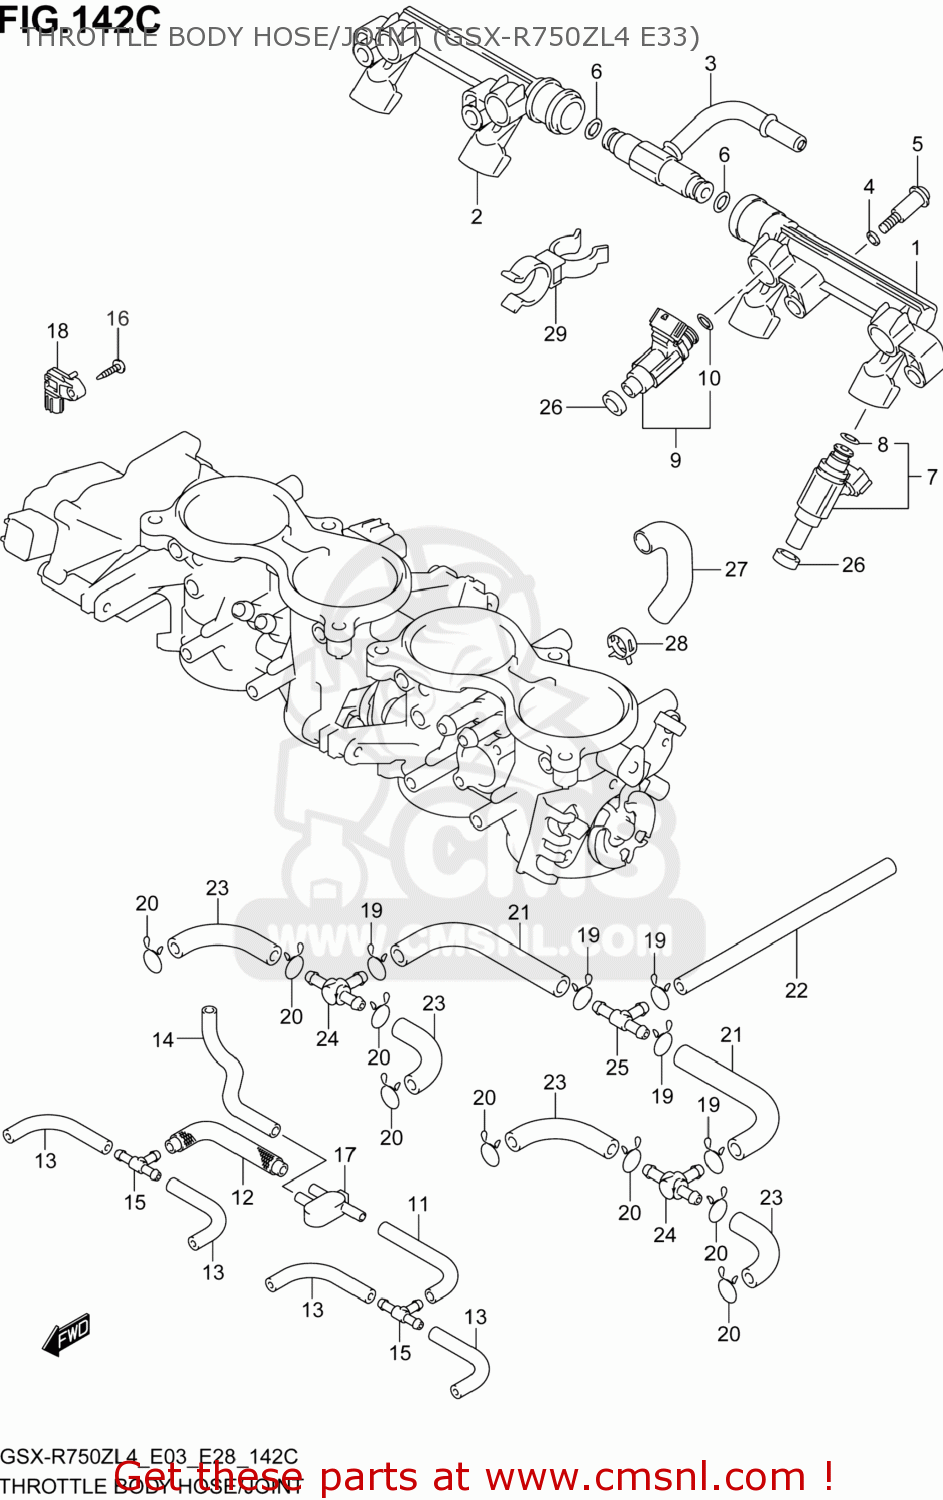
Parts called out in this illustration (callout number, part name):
1	DELIVERY PIPE
2	DELIVERY PIPE
3	NIPPLE ASSY
4	PACKING (NAS)
5	SCREW
6	O RING
7	INJECTOR ASSY
8	O-RING
9	INJECTOR ASSY
10	O-RING
11	HOSE
12	HOSE
13	HOSE(L:425)
14	HOSE
15	3WAY,VACUUM HOSE
16	SCREW
17	JOINT
18	SENSOR,BOOST
19	CLIP
20	CLIP
21	HOSE
22	HOSE
23	HOSE
24	NIPPLE
25	NIPPLE
26	SEAL
27	HOSE
28	CLIP
29	CLAMP
